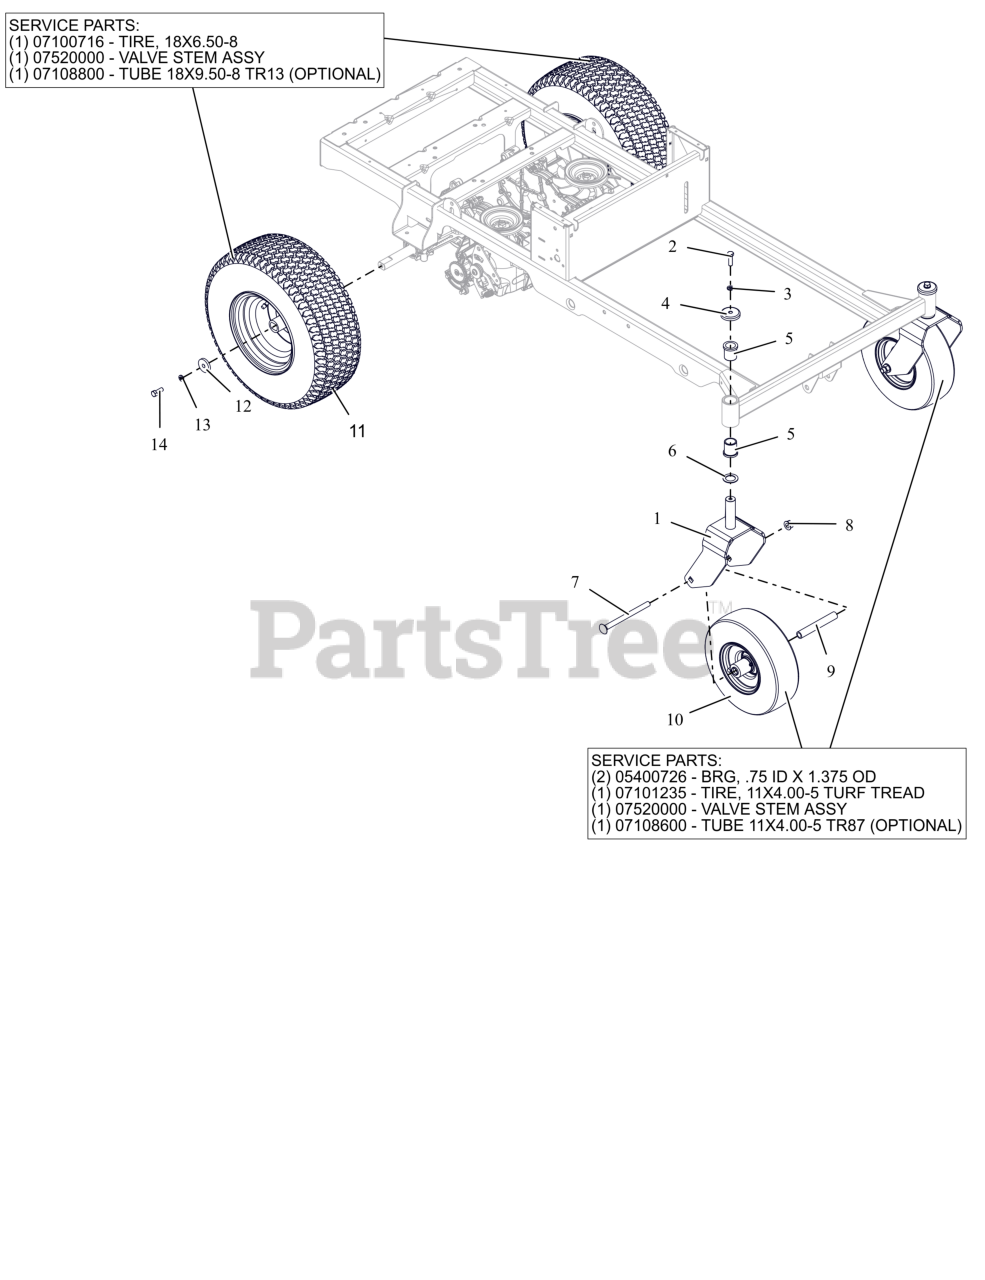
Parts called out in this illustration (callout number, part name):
1	WLDMT, CASTER FORK (RED)
2	BLT- HEX .38-16X1.25 G5 ZB500
3	WSHR-LK-REG .375X.094 ZB500
4	SHIELD, AXLE BEARING BLK
5	BSHG-FLG 1.00X1.25X1.50X1.50
6	WSHR-HRD-THRS 1.007X1.542X.062
7	BLT, RHSN .50-13X6.50 G5 ZCC
8	NUT-LK-CTR-FLG .500-13 GG ZCC
9	SPACER, ROLLED WHEEL
10	ASM, WHL/TIRE 11X4.00-5 LG BLK
10	BRG, .75 ID X 1.375 OD
10	TIRE, 11X4-5 TURF TREAD
10	VALVE STEM ASS'Y
10	TUBE 11 X4.0-5 TR87
11	ASM, WHL/TIRE 18X6.50-8 LG BLK
11	TIRE, 18X6.5-8
11	VALVE STEM ASS'Y
11	TUBE 18X6.50/8.50/9.50-8/20X8.00/10.00-8
12	WSHR, FLT .406X1.50X.245 ZCC
13	WSHR,LK-REG .375X.094 ZCC
14	BLT, HEX .38-16X1.00 G8ZCCEP30
